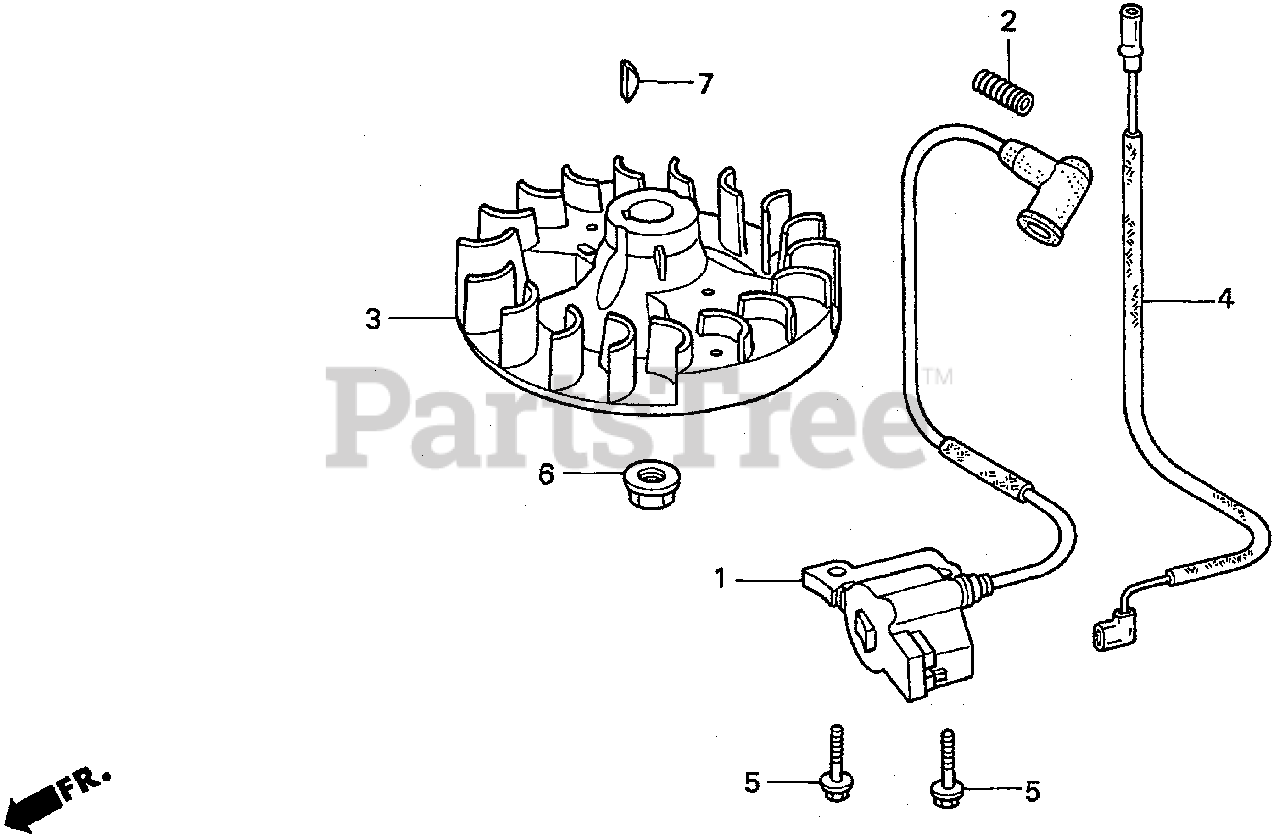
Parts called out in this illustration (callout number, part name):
1	COIL ASSY., IGNITION
2	TUBE A, CORRUGATED (7X18)
3	FLYWHEEL COMP.
4	WIRE, STOP SWITCH
5	BOLT-WASHER (5X16)
6	NUT, FLANGE (10MM)
7	KEY, WOODRUFF (16X12)
